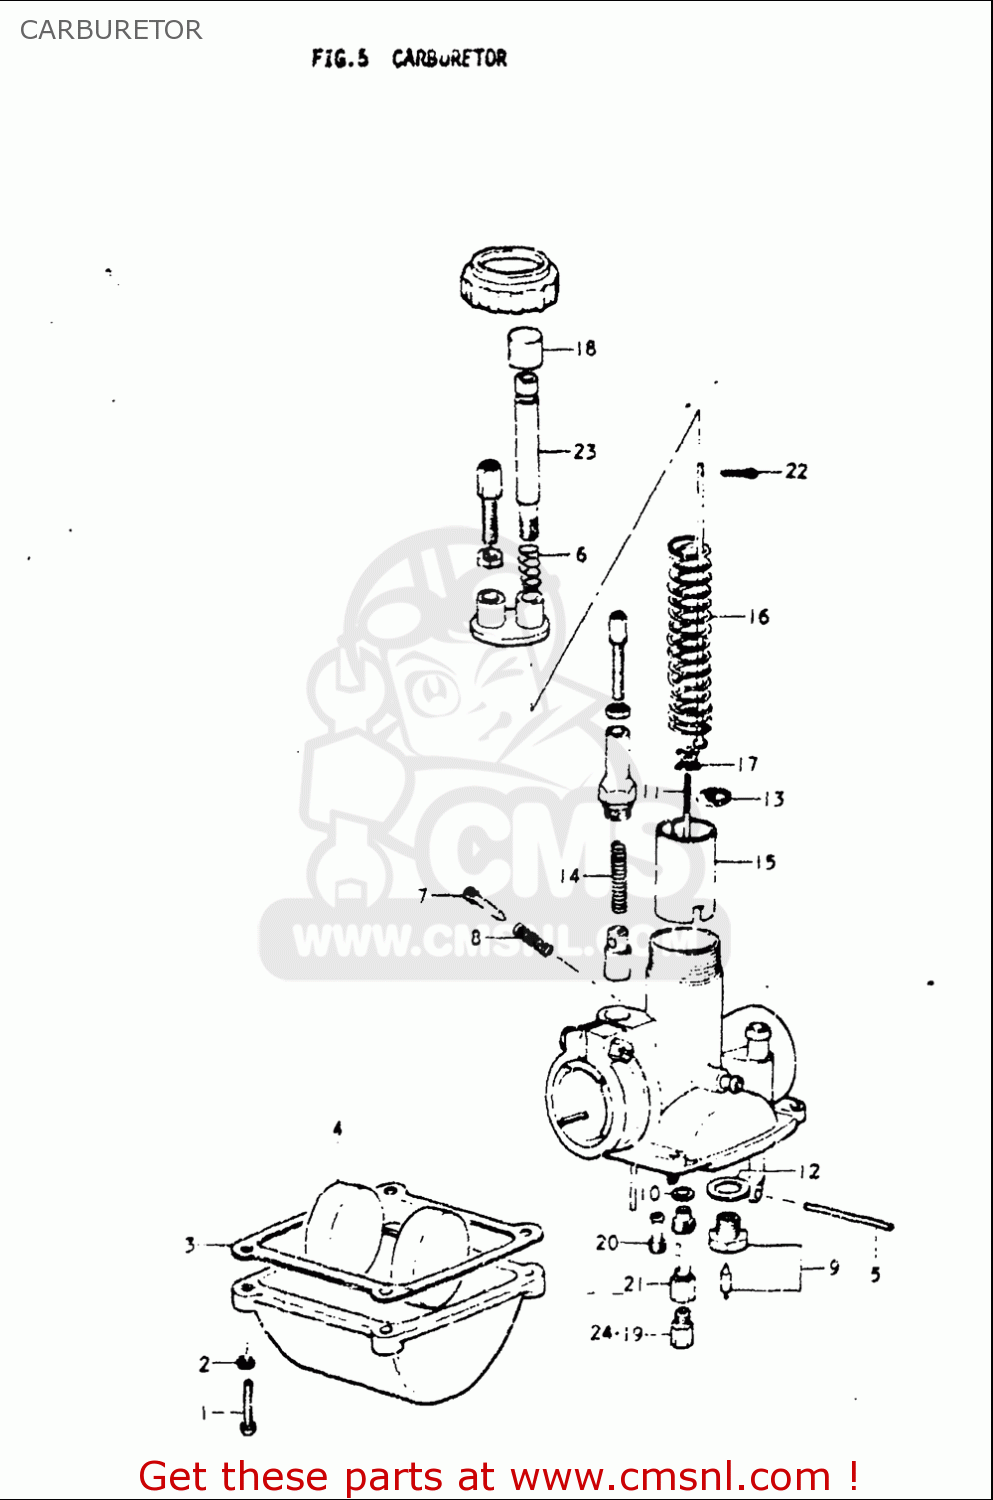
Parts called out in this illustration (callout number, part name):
1	SCREW
2	WASHER,LOCK
3	GASKET,FLOAT CHAMBER (NAS)
4	FLOAT
5	PIN,FLOAT
6	SPRING,THROTTLE STOP SCREW
7	SCREW,PILOT AIR
8	SPRING
9	VALVE ASSY,NEEDLE
10	WASHER
11	NEEDLE,JET
12	GASKET,NEEDLE VALVE (NAS)
13	CLIP,NEEDLE
14	SPRING
16	SPRING,THROTTLE VALVE
17	STOPPER,NEEDLE CLIP
18	CAP,THROTTLE VALVE STOP SCREW
19	JET,MAIN
20	JET,PILOT(35)
21	JET,NEEDLE
22	PIN 12X10
23	SCREW,THROTTLE STOP
24	JET,MAIN
